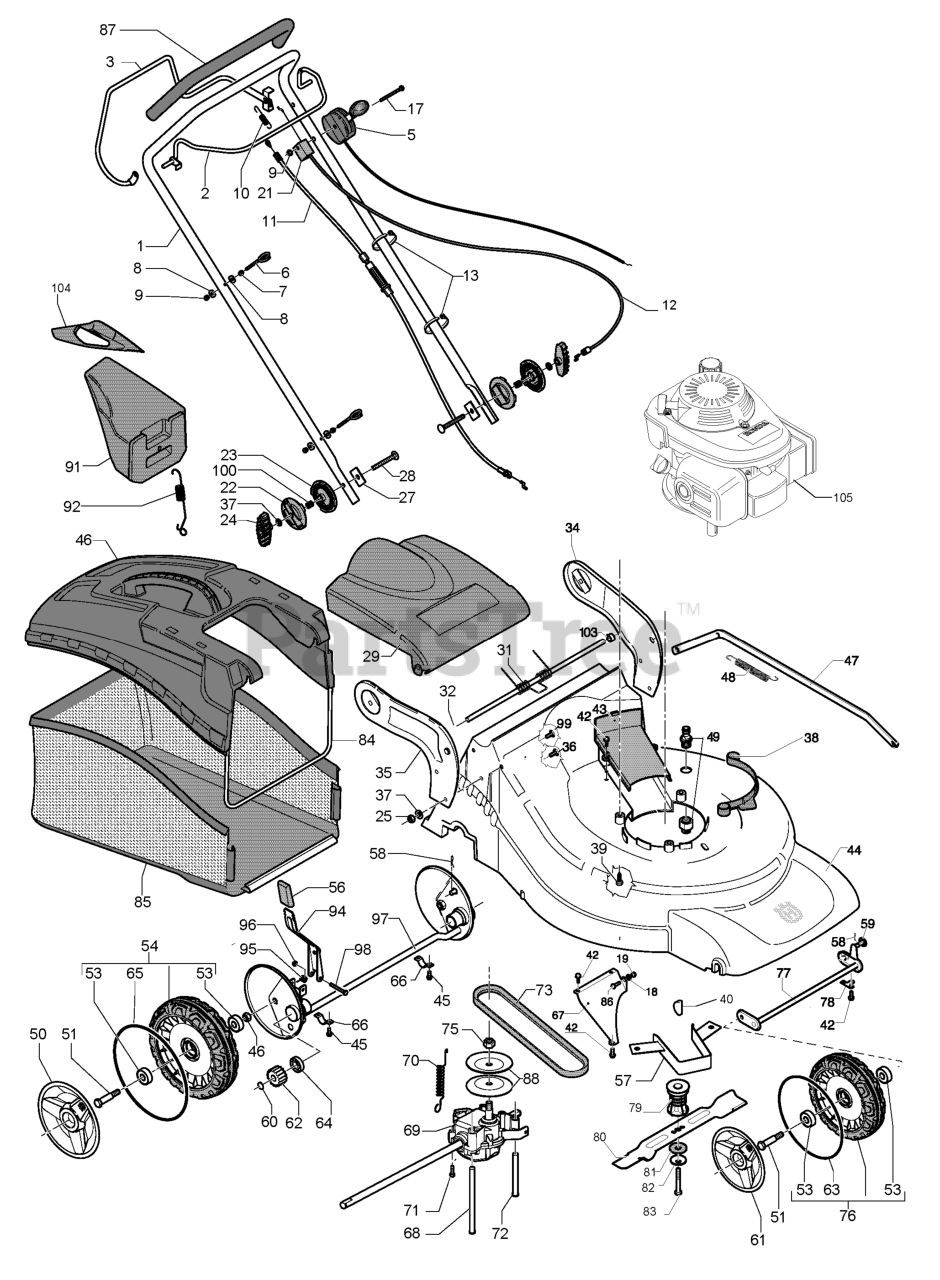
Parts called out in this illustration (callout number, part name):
12	BRAKE WIRE
29	DEFLECTOR 51 CAST ORANGE
31	SPRING 51 CAST
46	COVER HARD TOP
84	FRAME 51 CAST
97	REAR AXLE REAR AXLE WELDED FOR
